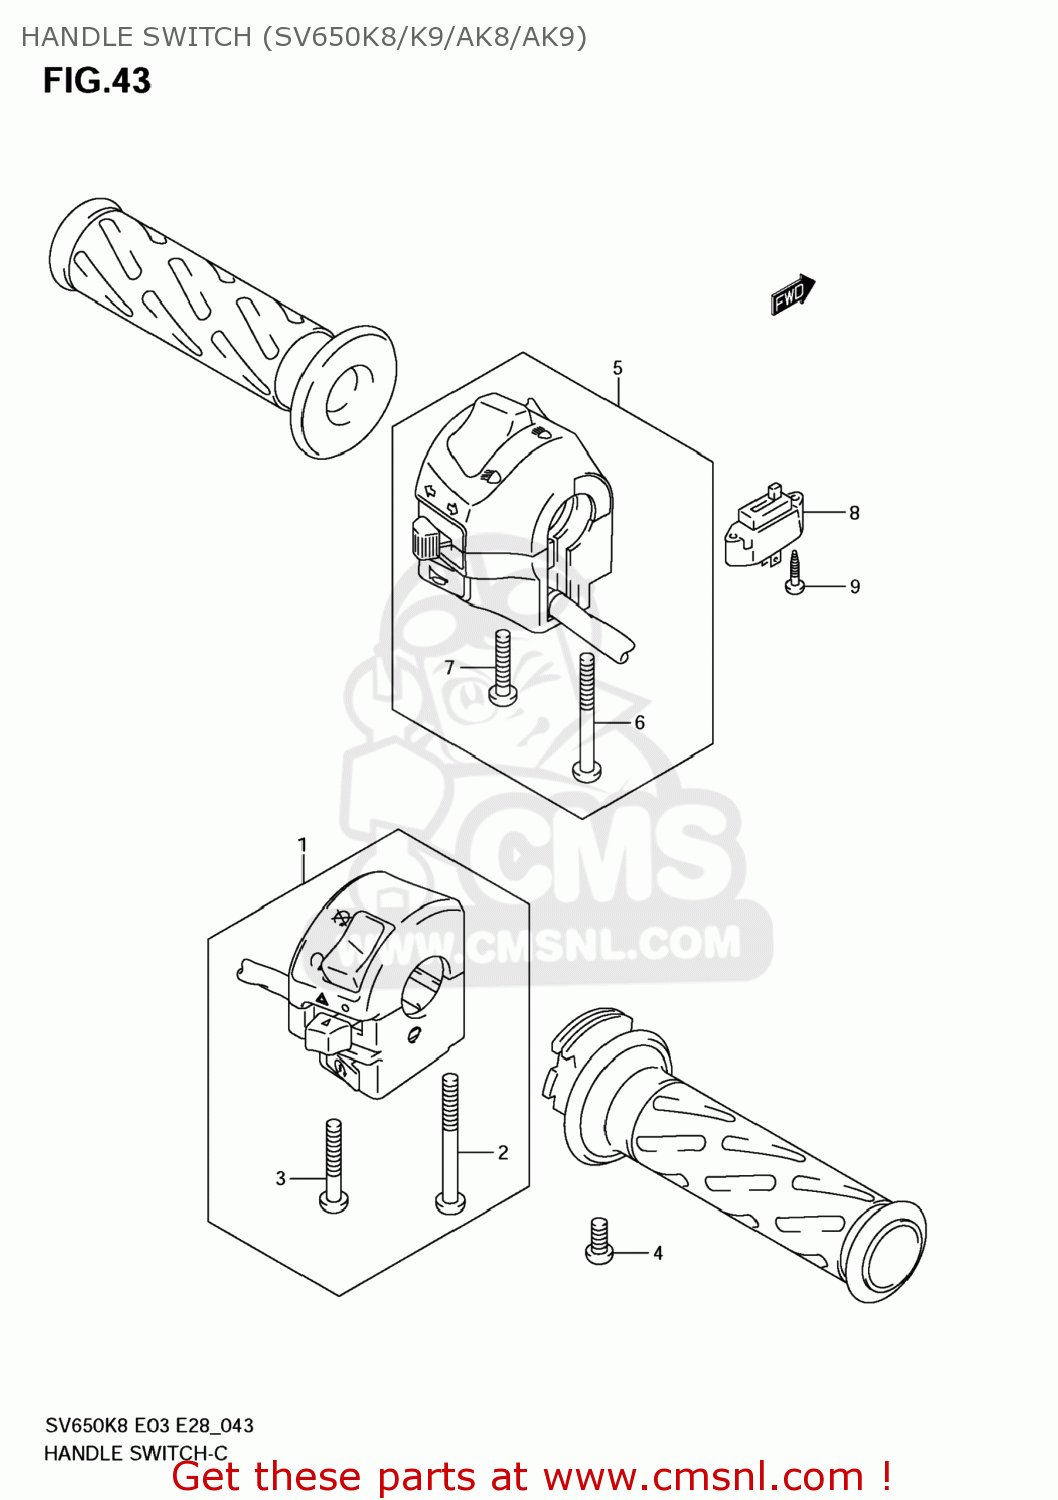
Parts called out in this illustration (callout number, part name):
1	SWITCH ASSY,HANDLE,R
2	SCREW
3	SCREW
4	SCREW
5	SWITCH ASSY,HANDLE,L
6	SCREW, 5X45
7	SCREW(5X25)
8	SWITCH ASSY,CLUTCH
9	SCREW(3X14)
